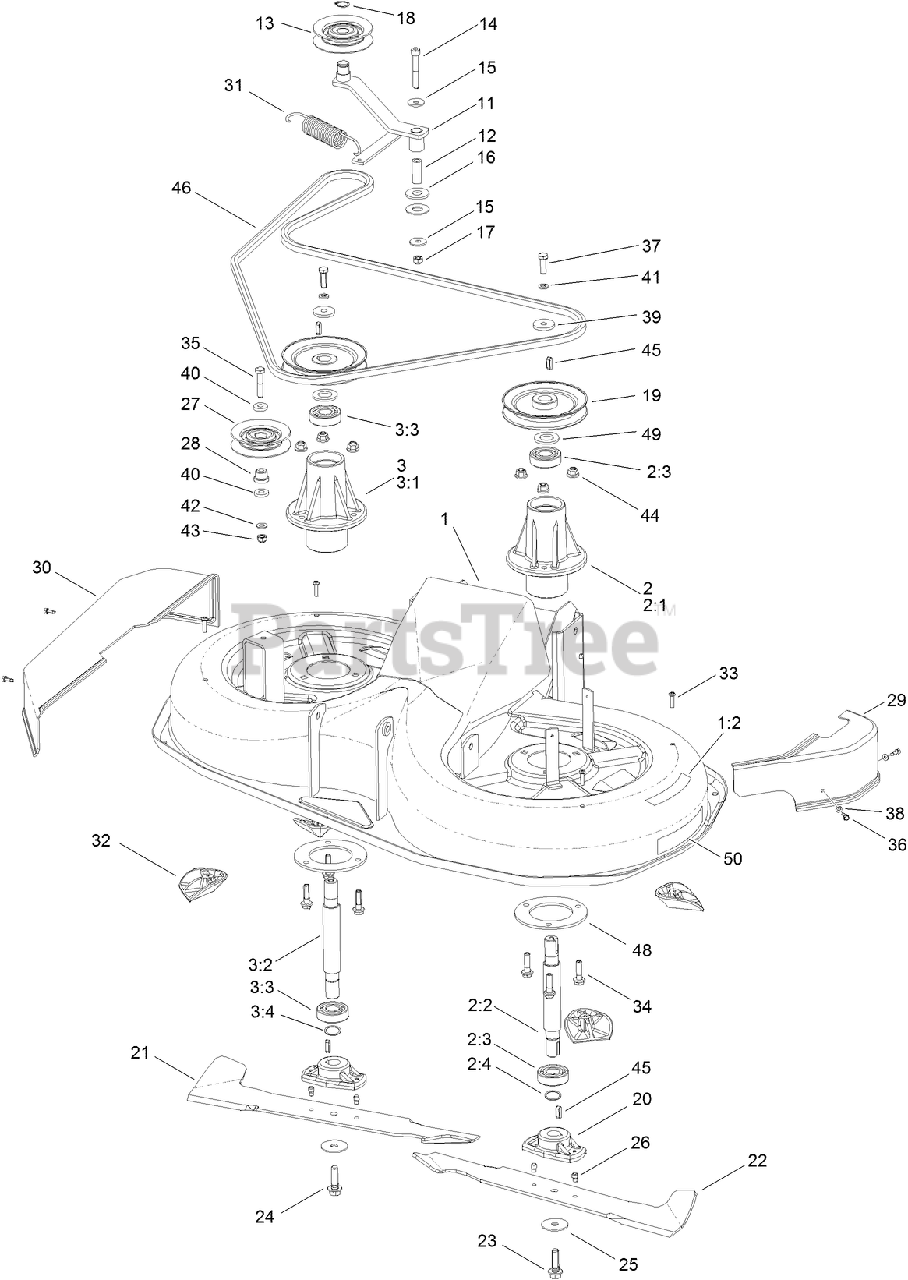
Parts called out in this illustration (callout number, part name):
1	DECK ASM
1:2	DECAL-DANGER
2	LEFT SPINDLE ASM
2:1	HOUSING-SPINDLE
2:2	SHAFT-BLADE, LEFT
2:3	BEARING
2:4	RING-LOCK
3	RIGHT SPINDLE ASM
3:1	HOUSING-SPINDLE
3:2	SHAFT-BLADE, RIGHT
3:3	BEARING
3:4	RING-LOCK
11	ARM-IDLER
12	SPACER
13	PULLEY-IDLER
14	BOLT-HH
15	WASHER-PLAIN
16	WASHER-PLAIN
17	NUT-LOCK, NI
18	RING-LOCK
19	PULLEY-MOWING BELT, 4.5IN
20	ADAPTER-MOUNT, BLADE
21	BLADE-RH
22	BLADE-LH
23	SCREW-HEX
24	SCREW-HH, LEFT
25	WASHER-BELLEVILLE
26	PIN-SHEAR, GROOVED
27	PULLEY-IDLER
28	BUSHING
29	GUARD-BELT, LEFT
30	GUARD-BELT, RIGHT
31	SPRING
32	KICKER
34	SCREW-HHF
35	SCREW-HH
37	SCREW-HH
38	WASHER
39	WASHER
40	Washer-Flat
41	WASHER-SPRING
42	WASHER-PLAIN
43	NUT-LOCK, NI
44	NUT-LOCK, HHF
46	BELT-WEDGE, DOUBLE
48	SUPPORT-RING
49	WASHER-PLAIN
50	DECAL-RECYCLER
